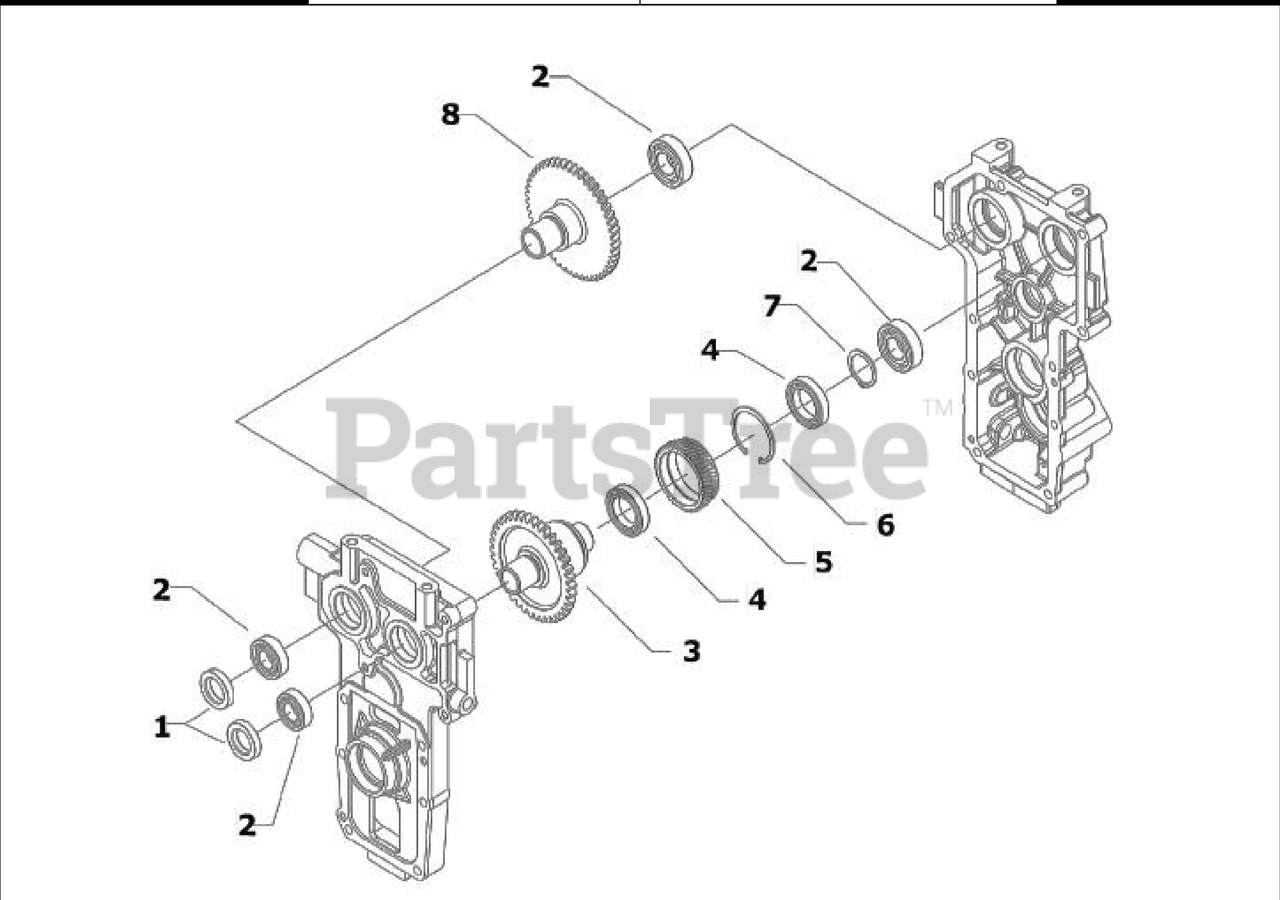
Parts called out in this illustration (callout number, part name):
1	OIL SEAL 20X35X7
2	BEARING 6004 (20X42X12)
3	GEAR
4	BEARING 61908 (40x62x12)SKF
5	IDLER GEAR
6	SNAP RING I 62 DIN 472
7	SNAP RING E 36 UNI 7435
8	PUMP GEAR
